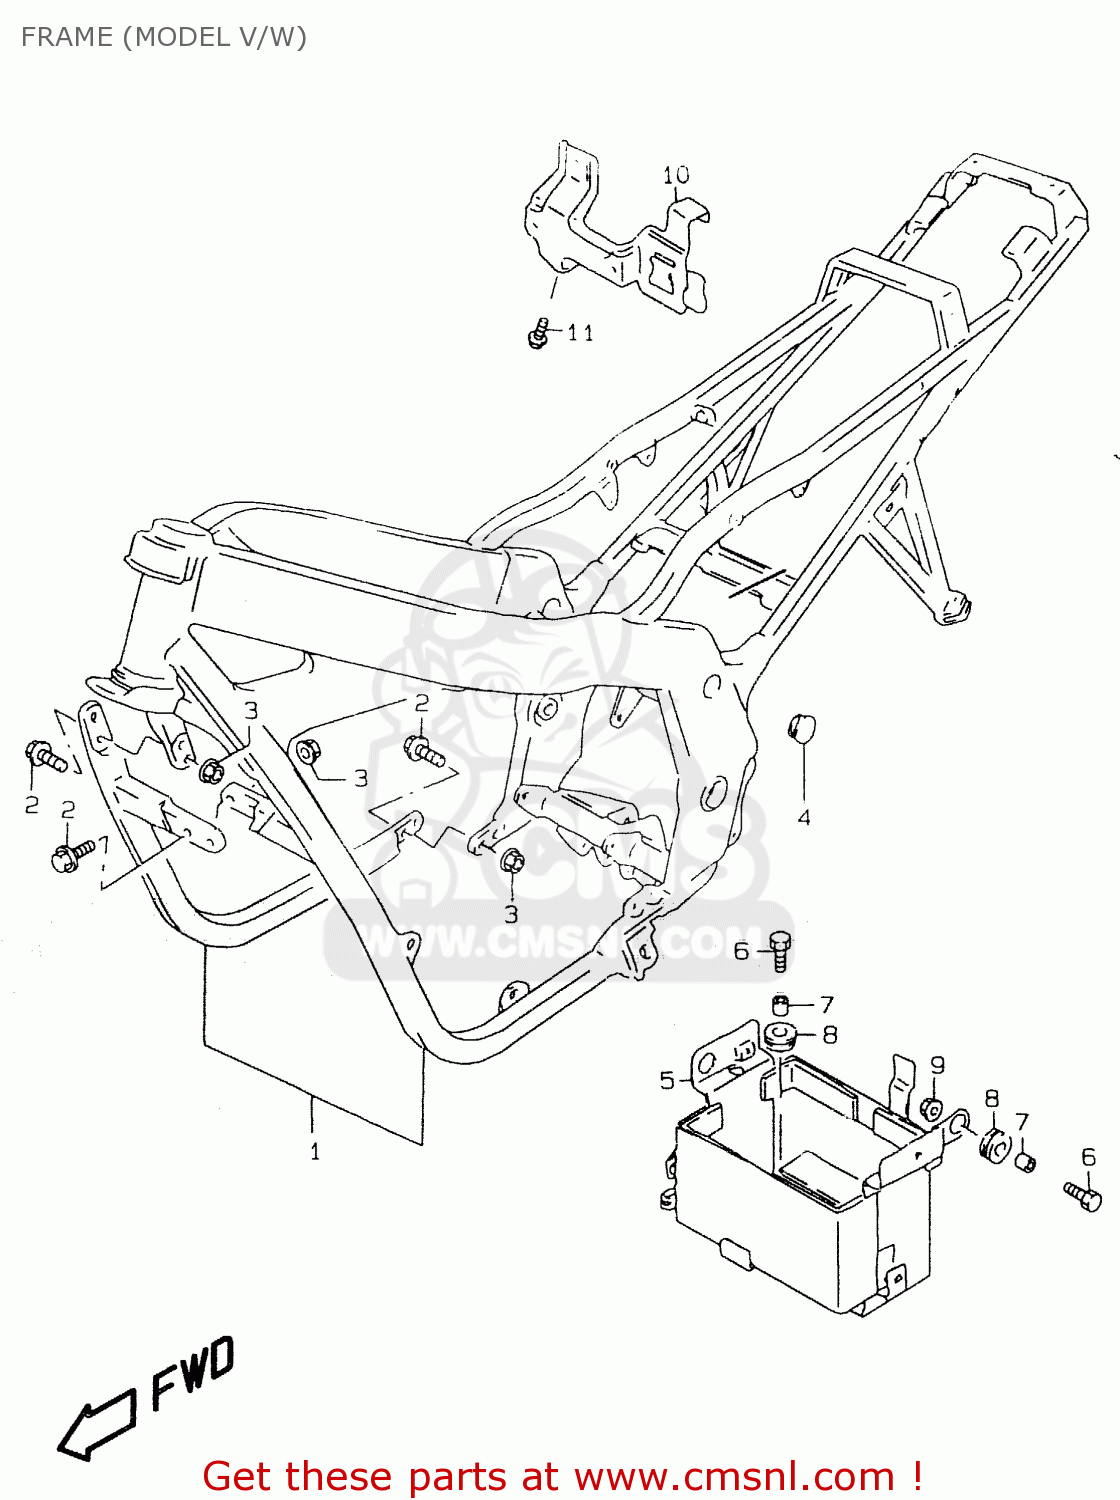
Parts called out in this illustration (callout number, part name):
1	FRAME SET
2	BOLT
3	NUT
4	CAP,BODY FRAME
5	HOLDER,BATTERY
6	BOLT(6X20)
7	SPACER(6.1X9X7.5)
8	CUSHION
9	NUT
10	HOLDER,ELECTRIC PARTS
11	BOLT
